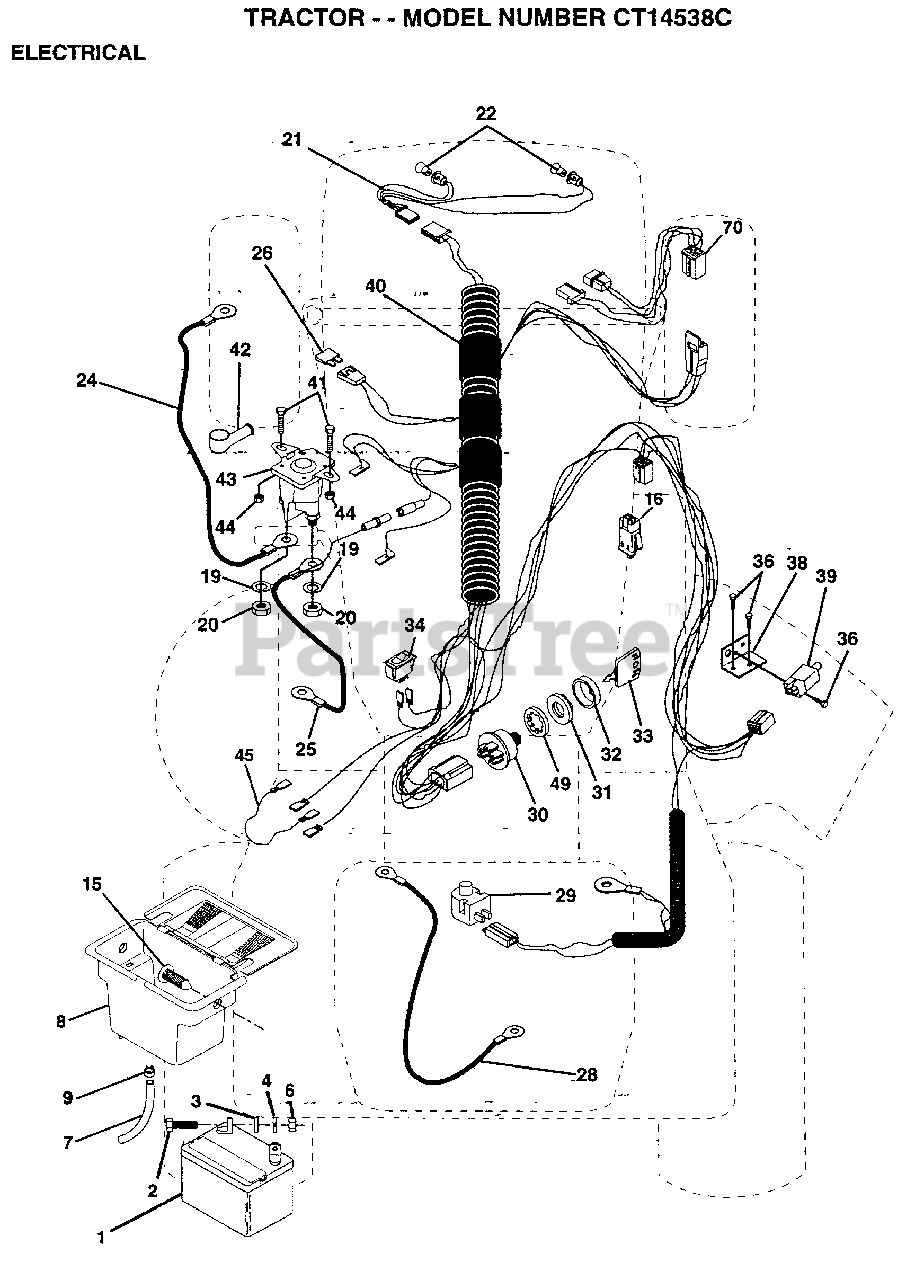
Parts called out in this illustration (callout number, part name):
2	BOLT LT
3	WASHER
4	LOCKWASHER
7	TUBE T
9	HOSE CLAMP T
15	FASTNER.SNAP-IN
16	SWITCH INTERLOCK
20	NUT
21	"HARNESS,LIGHT SOC"
22	HEADLAMP BULB
24	"CABLE T, BATTERY"
25	CABLE.BTRY.6GA.RD
26	FUSE HYT
28	CABLE T
29	SWITCH SEAT
32	COVER KEY SWITCH
33	KEY MLD GEN DELTA
34	SWITCH LT
36	SCREW
38	BRACKET SWITCH IN
39	SWITCH INTERLOCKT
40	HARNESS.IGN.DASH.
41	BOLT HXHD FIN
44	NUT
45	ADAPTER AMMETER
49	WASHER PINNED
70	HARNESS.ENG.DUAL
